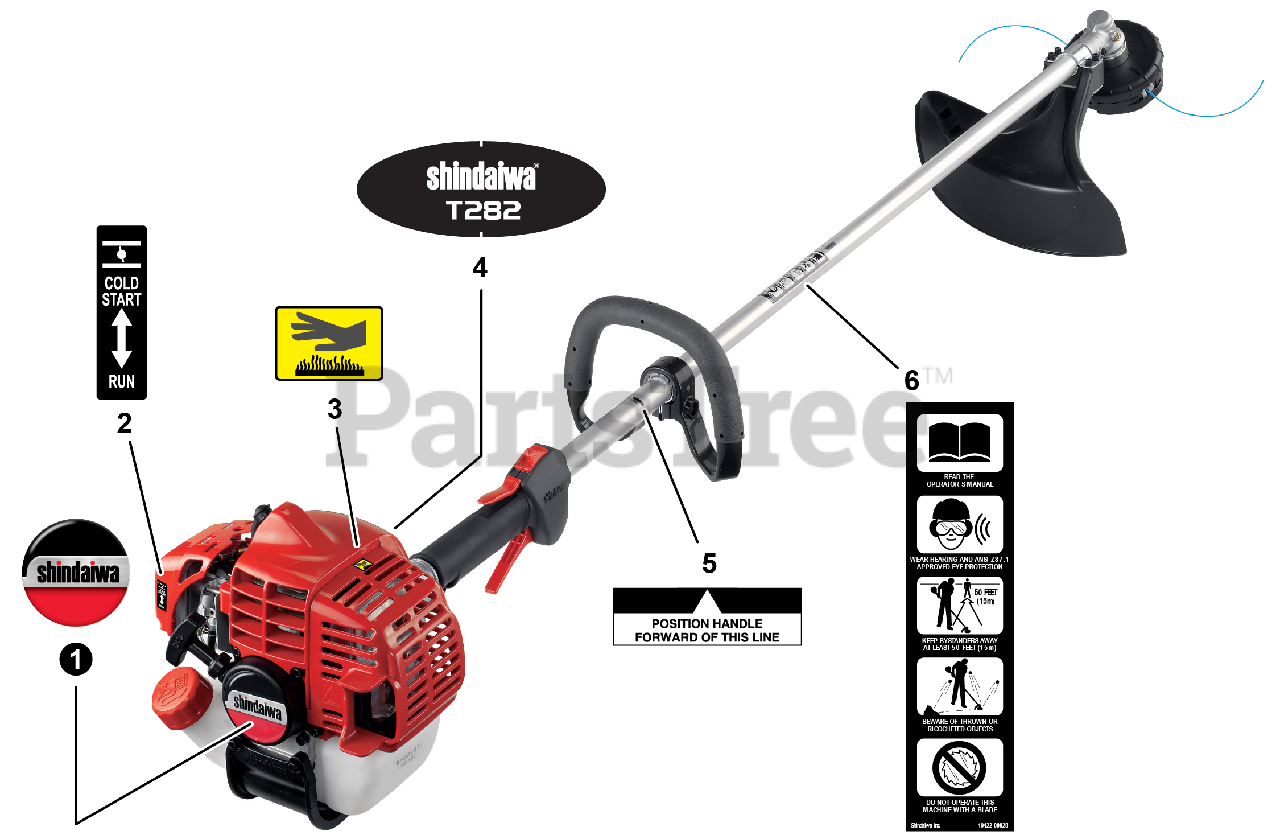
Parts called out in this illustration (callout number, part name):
1	LABEL, RECOIL STARTER
2	LABEL, CHOKE
3	LABEL, CAUTION - HOT
4	LABEL - MODEL T282
5	LABEL, HANDLE
6	LABEL, CAUTION
